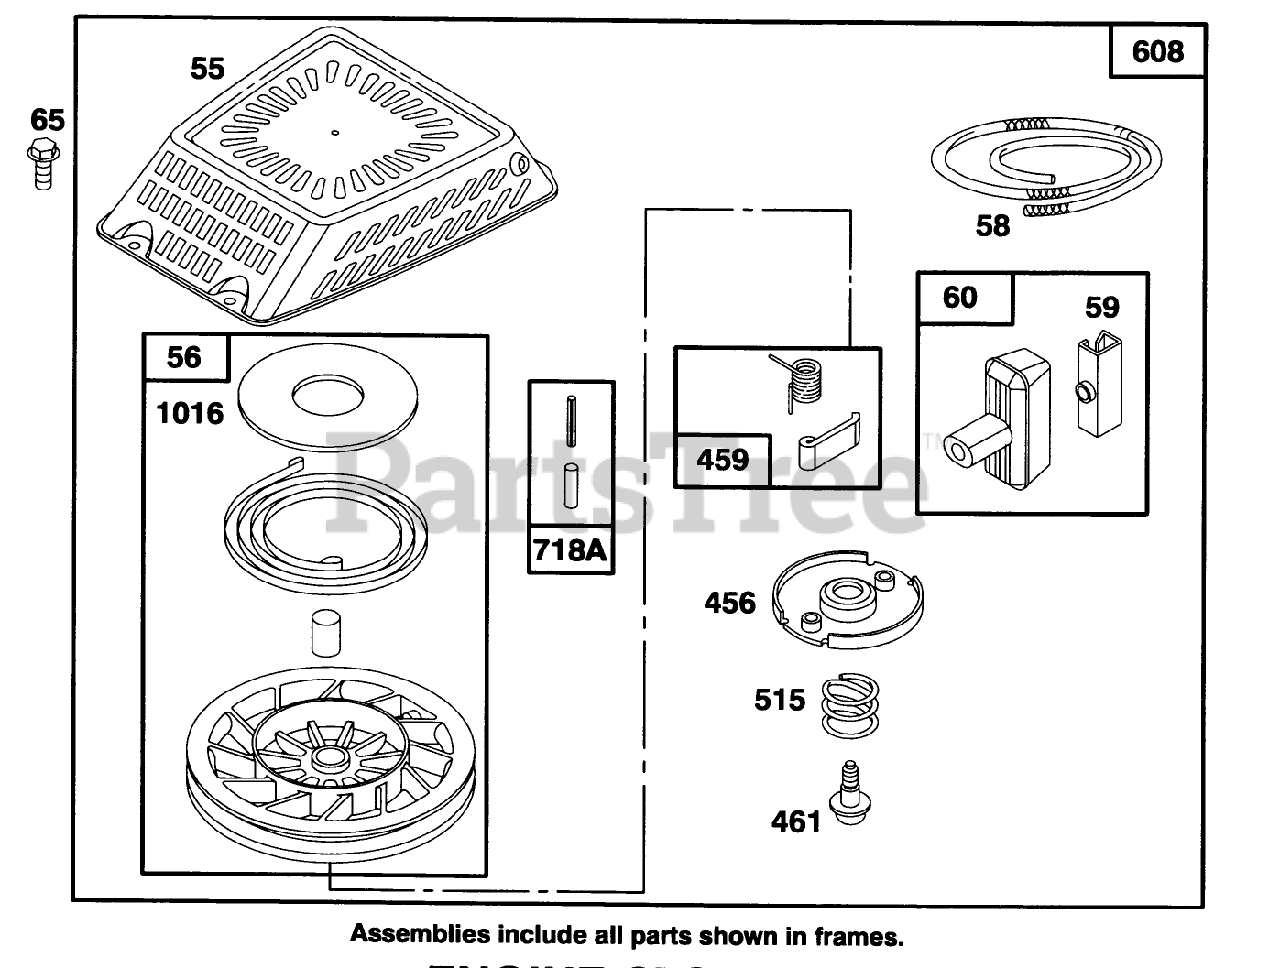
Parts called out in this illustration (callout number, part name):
59	INSERT-HANDLE, REWIND
456	RETAINER - SPRING
515	SPRING - RETAINER
